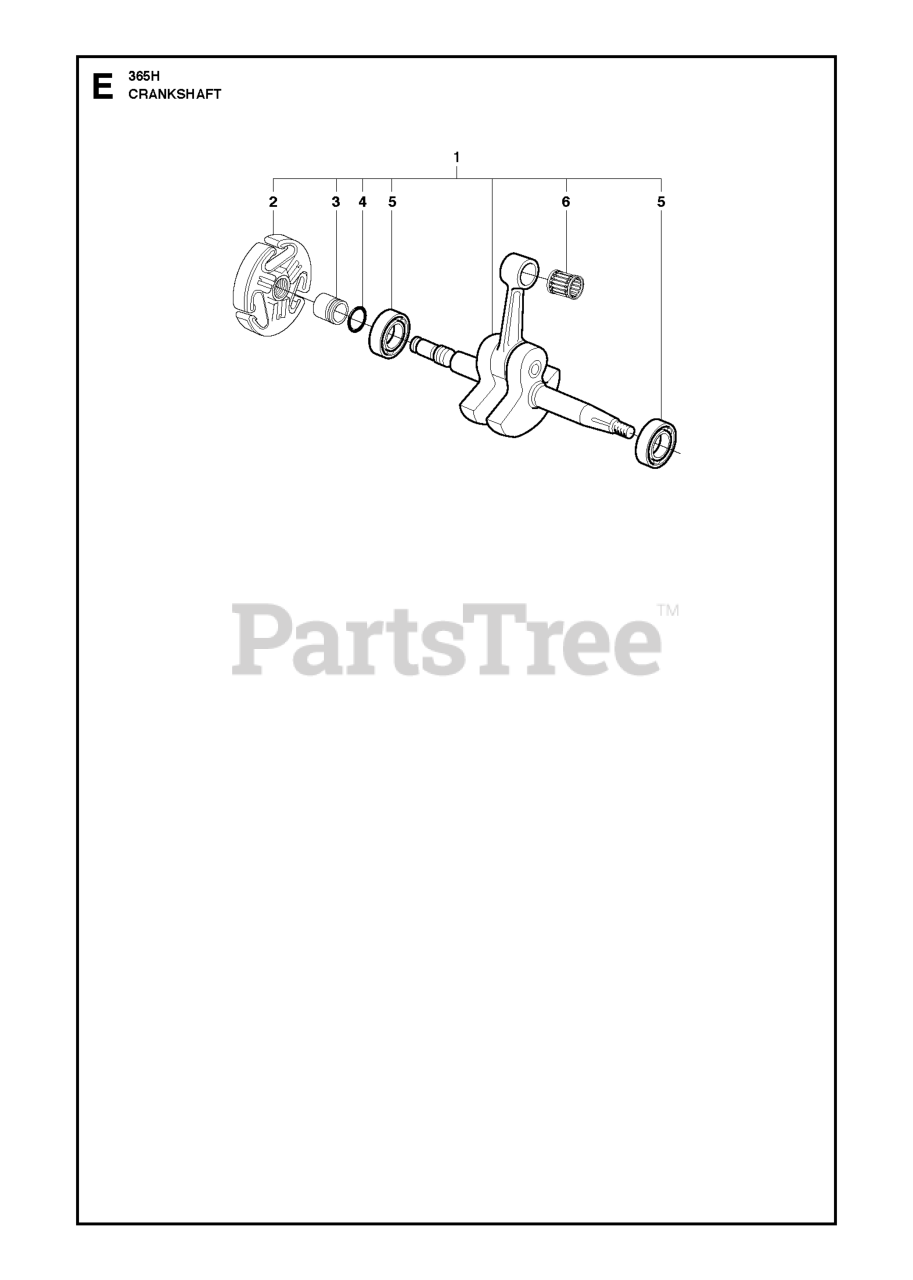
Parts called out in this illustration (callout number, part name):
2	CLUTCH
5	BALL BEARING
6	SUPPORT BUSHING
